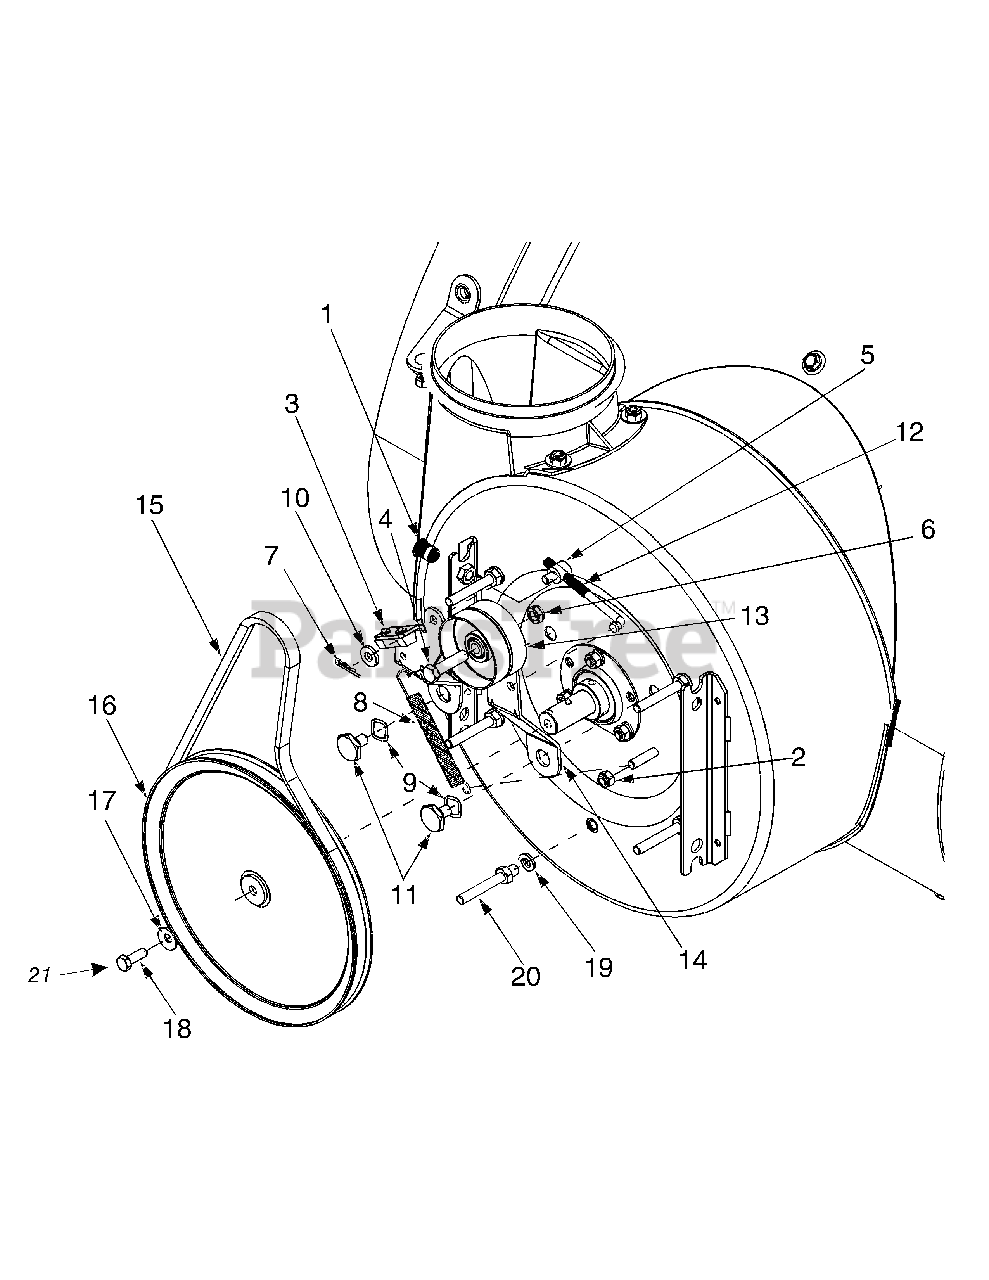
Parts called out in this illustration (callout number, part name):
1	Nut Insert 3/8-16 UNC
2	Hex Flg. L-Nut 5/16-18 Gr. F Nylon
3	Brake Bracket Ass’y (900 Series)
4	Hex Scr 3/8-24 x 1.50 Gr. 5
5	Adjustment Ferrule
6	Hex Nut 3/8-24 Gr. 5
7	Int. Cotter Pin .072 x 1.13" Lg.
8	Extension Spring .470 Dia. x 4.75
9	Wave Washer .625 ID x .885 OD x .015
10	Flat Washer .344 ID x .75 OD x .120
11	Shoulder Scr .625 Dia x .170
12	Auger Idler Rod
13	Flat Idler Pulley
15	V-Belt 1/2 x 44" Lg.
16	1/2" V-Pulley .875 ID x 10.12 OD
17	Cupped Washer .345 ID x .88 OD x .06
18	Hex Screw 5/16-18 x .88
19	Lockwasher 3/8" ID
20	Belt Keeper Studs 3/8-16 x 2.75
